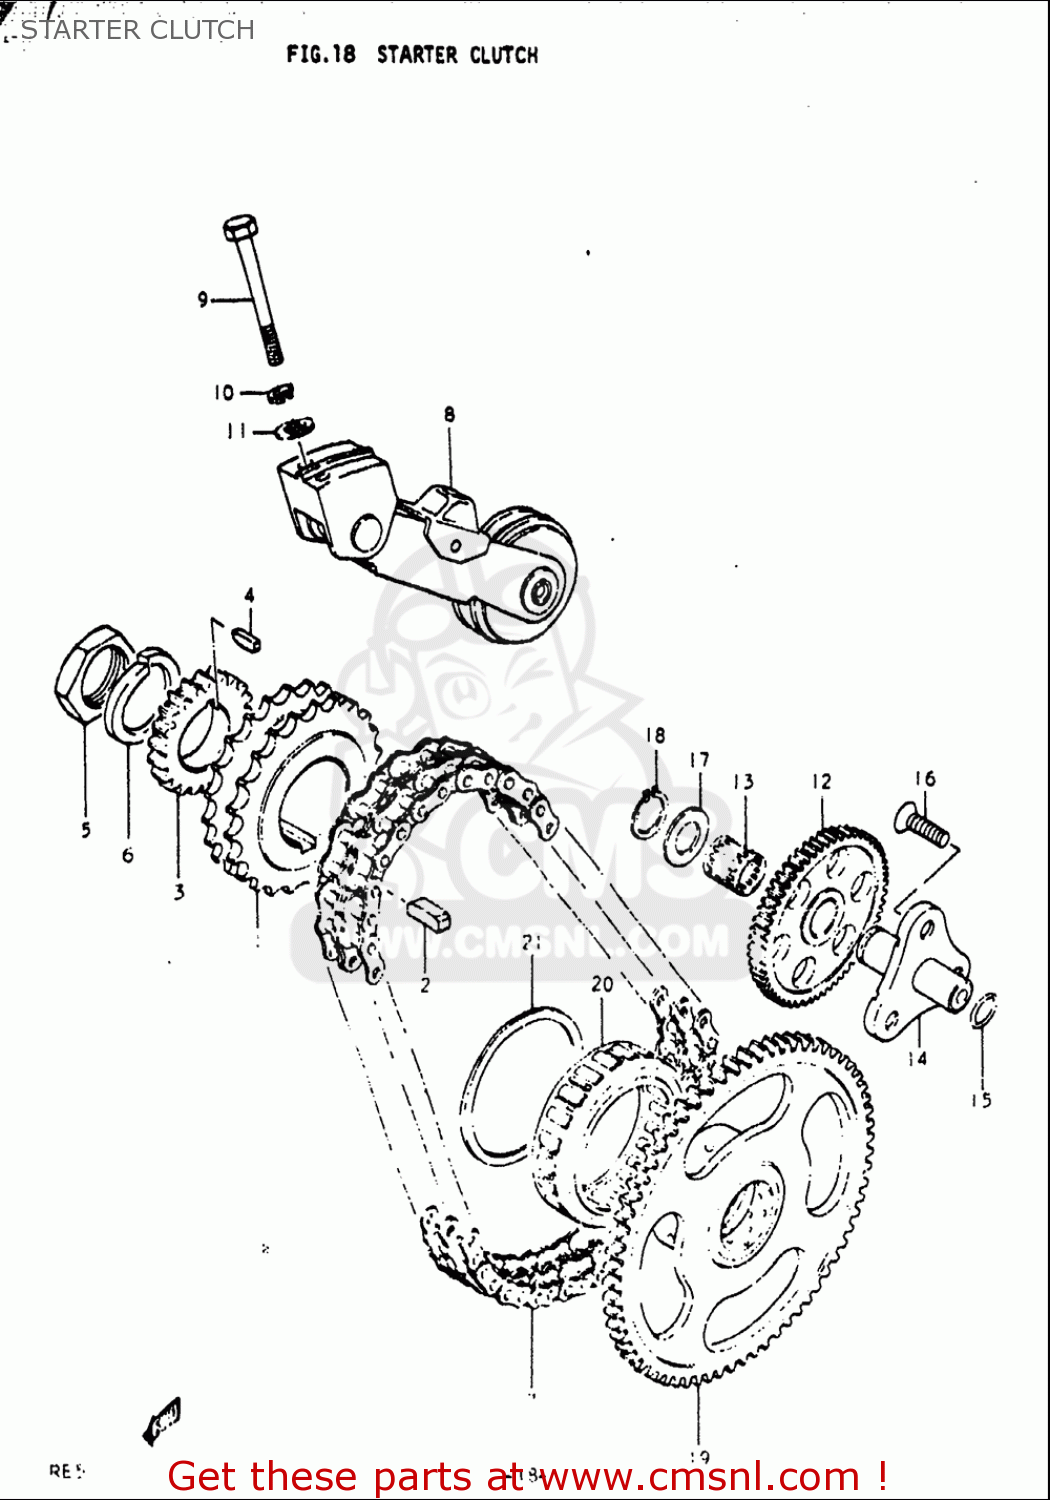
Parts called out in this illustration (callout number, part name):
2	KEY
4	KEY
9	BOLT
10	WASHER,LOCK
11	WASHER
13	BEARING(14X17X16.8)
15	O RING(D:1.3,ID:11.6)
16	SCREW
17	SHIM(14X22X1)
18	CIRCLIP
